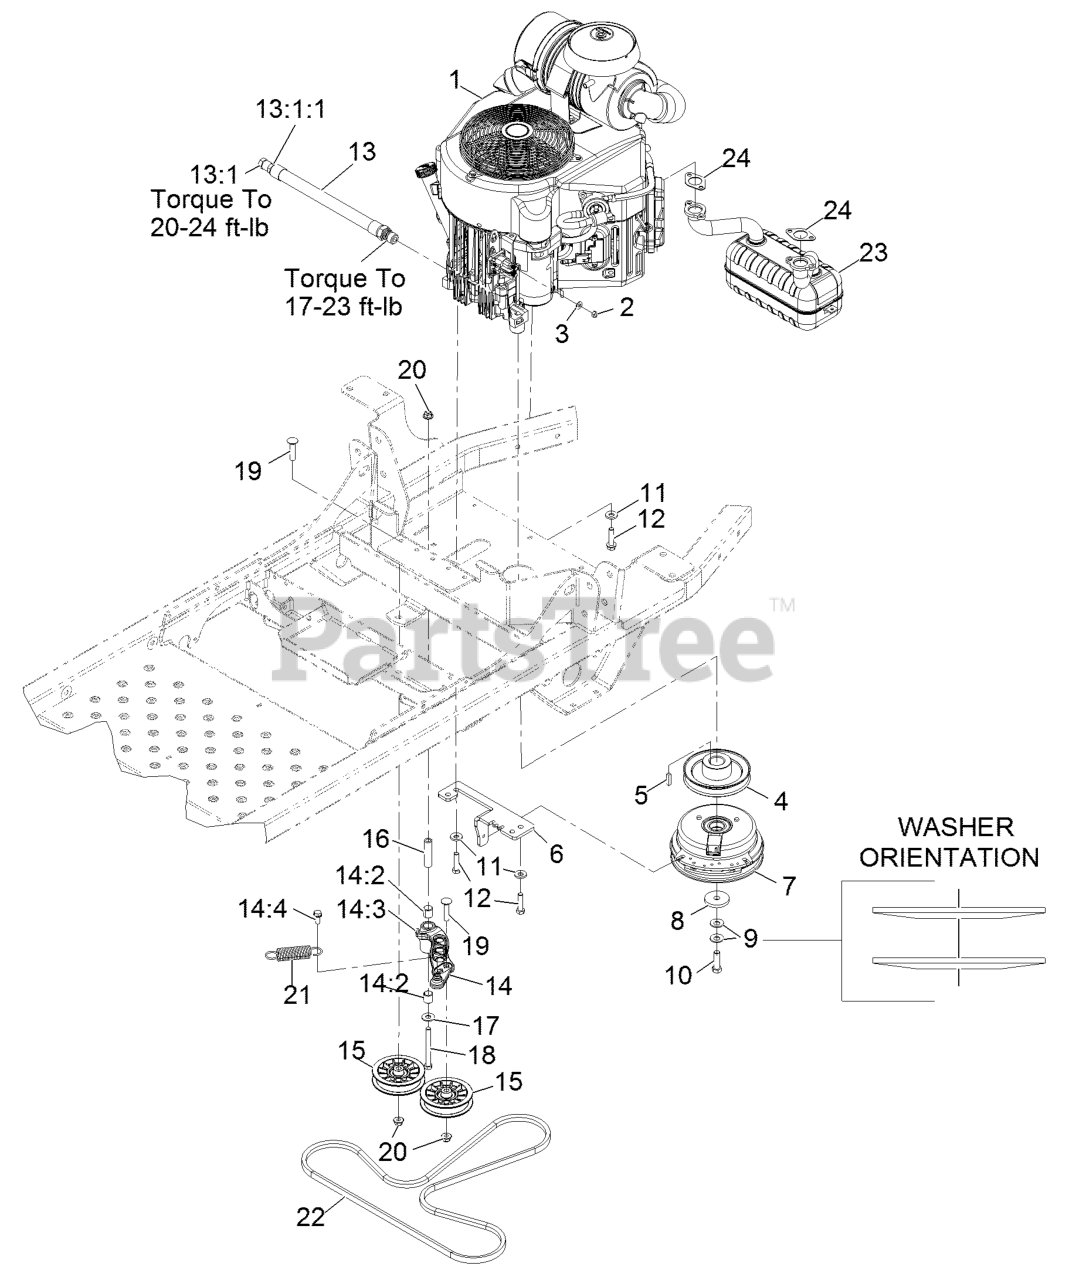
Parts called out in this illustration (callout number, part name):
2	NUT-HEX
3	WASHER-FLAT
4	SHEAVE-PUMP, DRIVE
6	ANCHOR-CLUTCH
8	WASHER-CLUTCH
9	WASHER-SPRING
10	SCREW-HH 7/16-20 X 1 1/2 W/LOCTITE
11	WASHER-BELLEVILLE
12	SCREW-HH
13	ENGINE OIL DRAIN HOSE ASM
13:1	PLUG-HH
13:1:1	O-RING
14	IDLER ARM ASM
14:2	SLEEVE-BEARING
14:3	FITTING-GREASE, 90 DEG
14:4	SCREW-THD ROLL, HWH
15	PULLEY-FLAT IDLER
16	BUSHING-PIVOT, IDLER
17	WASHER-FLAT
18	SCREW-CARR
19	SCREW-CARR
20	NUT-HF, NI
21	SPRING-EXTENSION
22	V-BELT
23	MUFFLER-KAWASAKI
24	GASKET-EXHAUST
